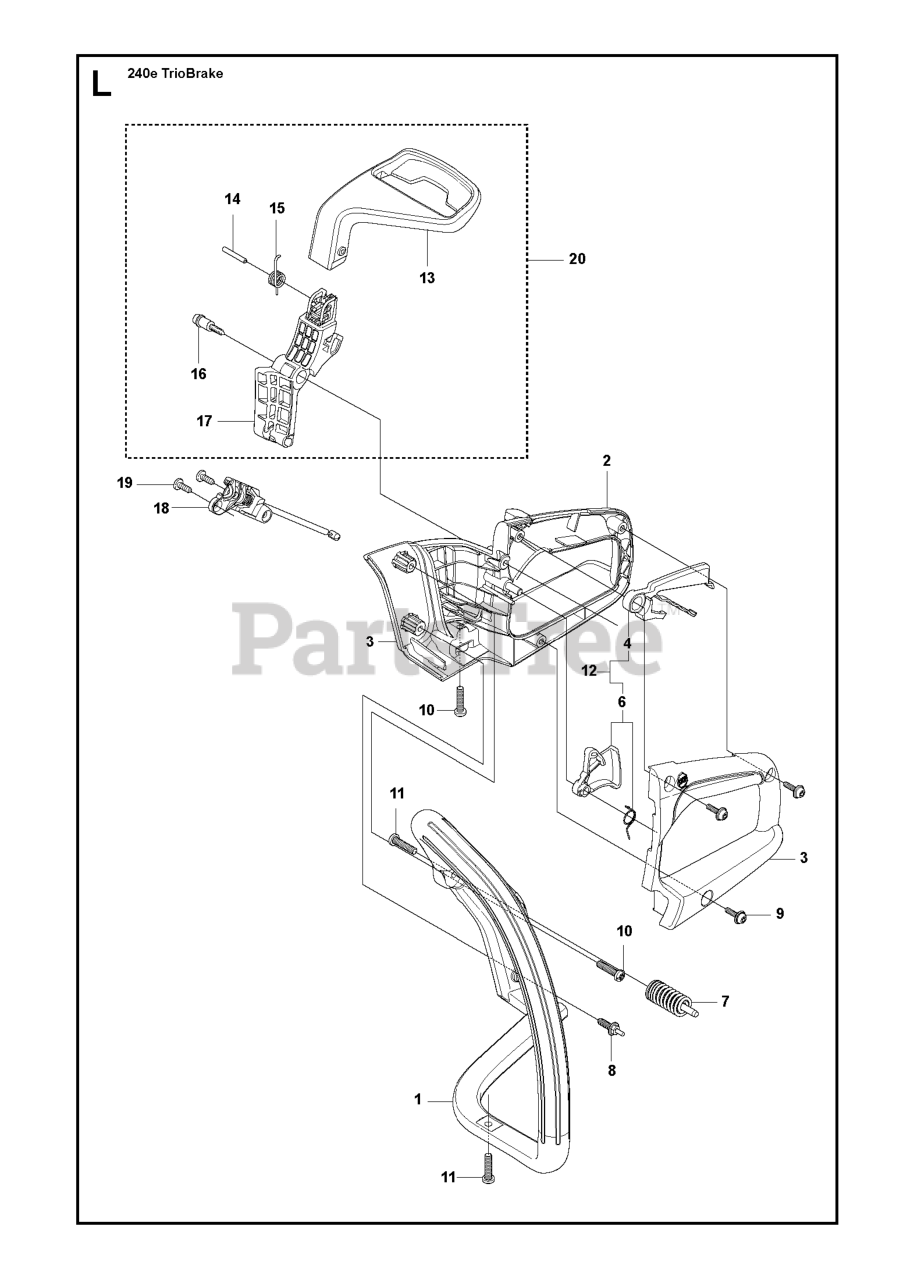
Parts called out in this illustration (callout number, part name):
1	FRONT HANDLE
2	REAR HANDLE
3	COVER REAR HANDLE
4	LOCKOUT - THROTTLE
6	TRIGGER & SPRING ASSY
7	SPRING CYLINDER ASSY
10	SCREW FILTER PLATE
11	SCREW M5.38-14X22.225MM
12	TRIGGER & LOCKOUT KIT
13	HAND GUARD
14	GROOVED PIN
16	SCREW SHOULDER
17	PIVOTING ARM
18	CABLE ASSY
19	SCREW 6-19X.437
20	REAR HANDGUARD ASSY
